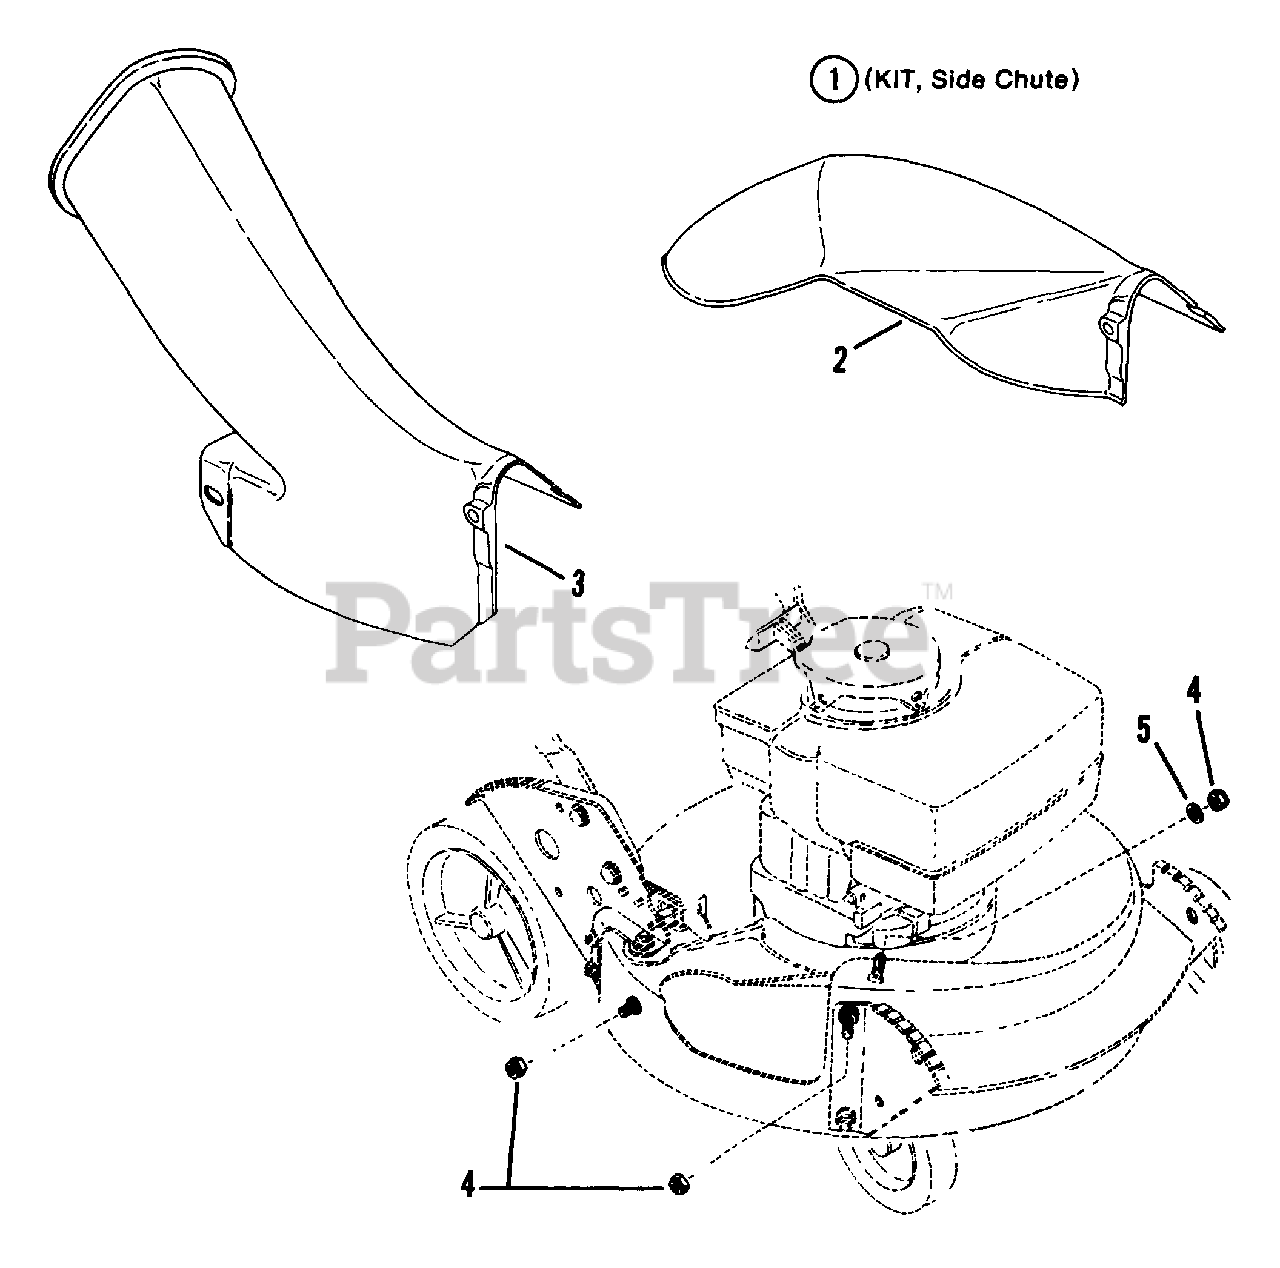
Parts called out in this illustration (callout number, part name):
1	KIT, Side Chute
2	CHUTE, Side
3	ADAPTER, Grass Bag Deck
4	NUT, 5/16-18 Hex Flange Lock
5	WASHER, 5/16 Flat
